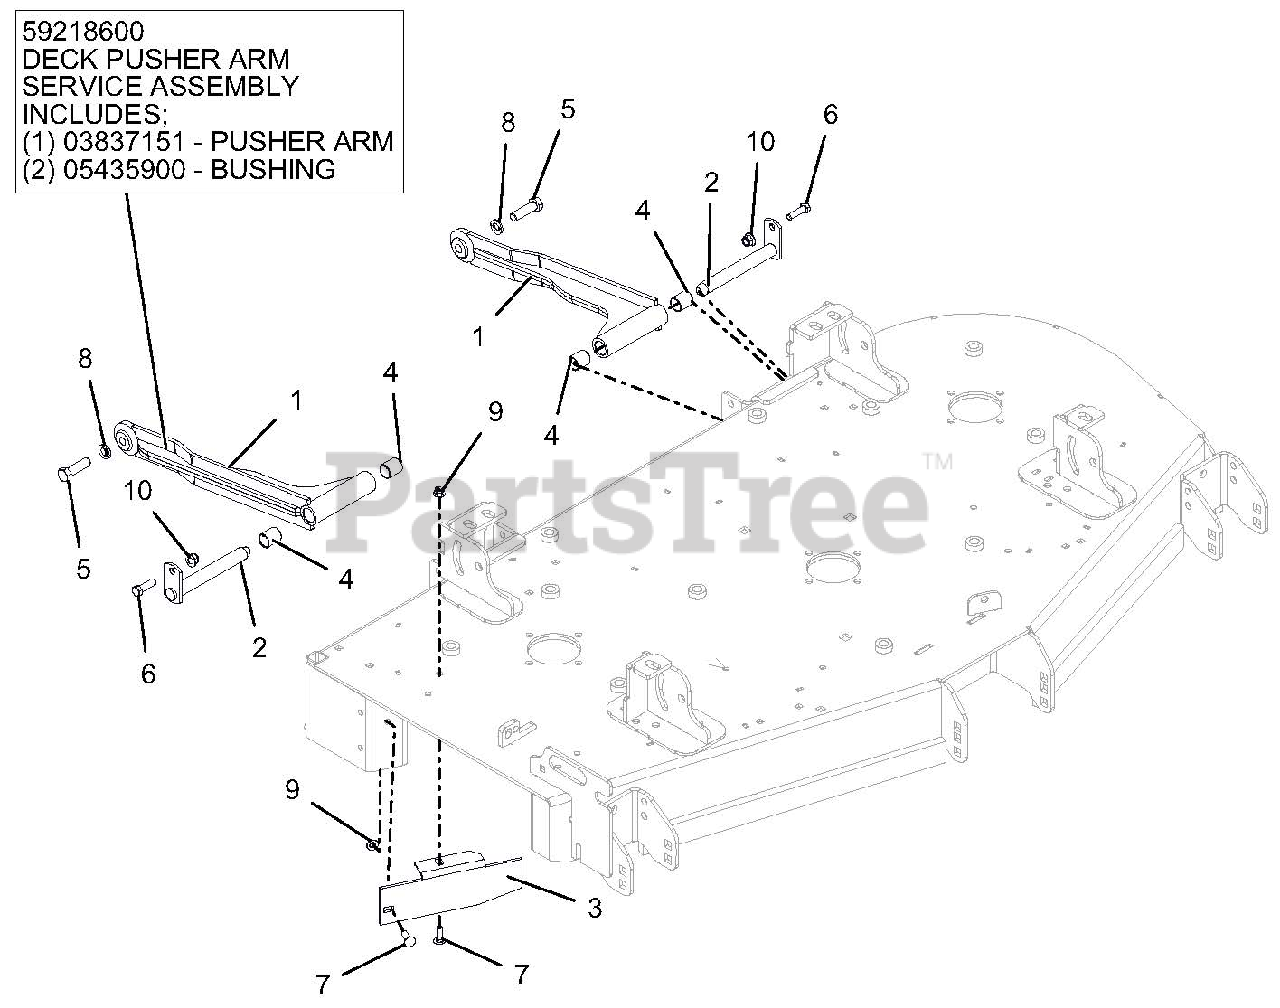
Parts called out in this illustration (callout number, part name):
1	DECK STABILIZER ARM - BLACK
1	DECK STABILIZER ARM W/BUSHINGS
1	BRG, .750 X .875 X 1.000
2	WELDMENT, MOWER MTG. PIN
3	52" DISCHARGE BAFFLE - RED
4	BRG, .750 X .875 X 1.000
5	BLT-HEX .50-13X1.75 GR5EP80 YZ
6	@BLT-HEX .38-16X1.25 GR5 YWZC
7	@BLT-RDHDSQNK .31-18X1.00 G5YZ
8	@WSHR-LK .50X.125 REG YWZC
9	@NUT-LK-NYL-FLG .31-18 YWZC
10	@NUT-LK-NYL-FLG .38-16 YWZC
